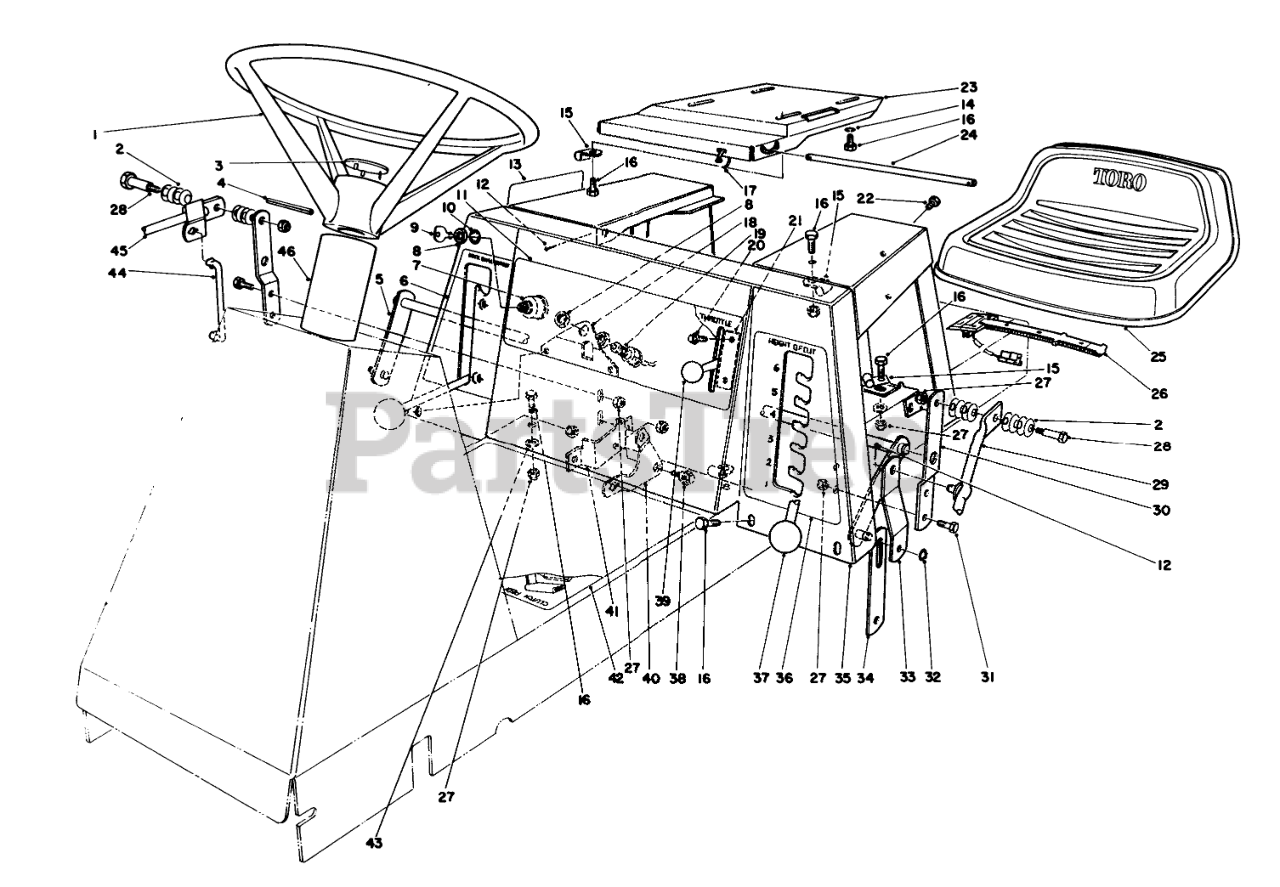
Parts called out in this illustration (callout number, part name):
1	Steering Wheel Assembly (Incl. Ref. #3)
2	WASHER-BELLEVILLE
3	Cap-Steering Wheel
4	PIN-ROLL
5	Arm
6	DECK ENGAGE DECAL
7	Switch-Ignition (Incl. Ref. #8-10)
8	NUT-HH
9	Key
10	WASHER-TOOTH, INTERNAL
11	IGN & THROTTLE DECAL
12	PIN-COTTER
13	Decal Shift Pattern
14	WASHER-LOCK
15	CLAMP
16	SCREW-HH
17	TIE-CABLE
18	SWITCH MT BRKT
19	Switch-Deck (Incl. Ref. #8)
20	SCREW-HWHTF
21	Throttle Control (Incl. Ref. #39)
22	SCREW-HH
23	SEAT BASE RO
24	SEAT BASE ROD
26	SWITCH-SEAT
27	NUT-LOCK, NI
28	BOLT-SHOULDER
29	HOC LEVER WA B
30	Bracket
31	SCREW-HH
32	RING-RETAINING
33	HOC ENGAGE BRKT R
34	DECK SUSP LINK B
35	Body-Seat
36	HOC DECAL
38	SCREW-SHOULDER
39	KNOB-CONTROL
40	DECK ENGAGE BELLCRANK
41	BELLCRANK MTG BRKT
42	INSTRUCTION DECAL
43	WASHER-PLAIN
44	BELLCRANK LINK(PLTD)
45	Lift Arm Assembly
46	STRG. SHAFT COVER
